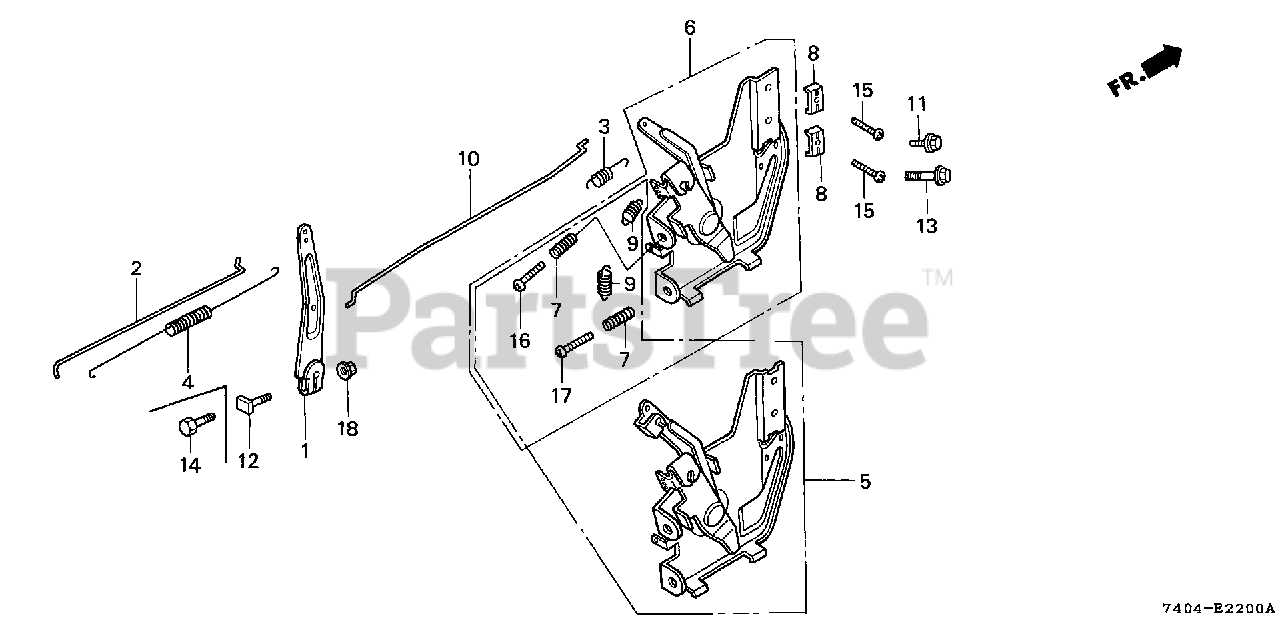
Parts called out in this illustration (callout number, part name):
1	ARM, GOVERNOR
2	ROD, GOVERNOR
3	SPRING, GOVERNOR
4	SPRING, THROTTLE RETURN
6	CONTROL ASSY.
7	SPRING, CONTROL ADJUSTING
8	HOLDER, CABLE
9	SPRING, CABLE RETURN
10	ROD, CHOKE
11	BOLT, FLANGE (6X12) (CT200)
13	BOLT, FLANGE (6X25)
14	BOLT, HEX. (6X18)
15	SCREW, PAN (5X16)
16	SCREW, PAN (5X18)
17	SCREW, PAN (5X22)
18	NUT, FLANGE (6MM)
